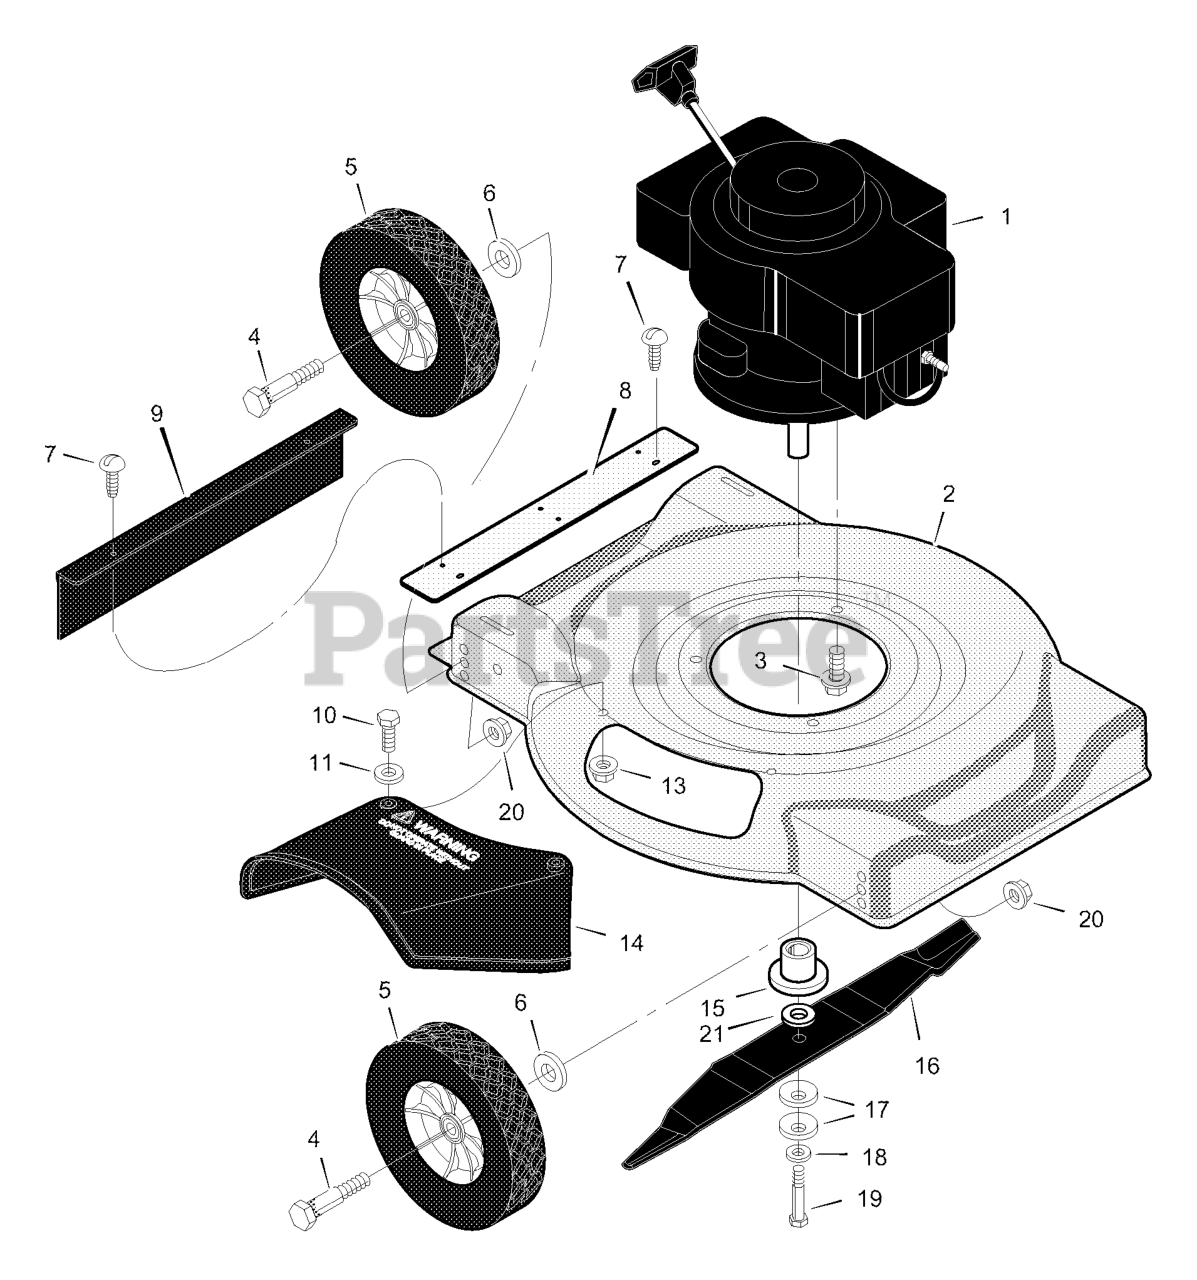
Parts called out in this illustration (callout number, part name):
1	Engine
3	Bolt, Engine
4	Bolt, Axle
5	WHEEL & TIRE ASSEMBLY
6	Washer
8	Extension, Rear
9	Deflector, Rear
11	Washer
13	Locknut
14	Deflector, Chute
15	Blade Adapter
16	Blade - 20"
17	Washer, Blade
18	Washer
19	Bolt
20	Locknut
